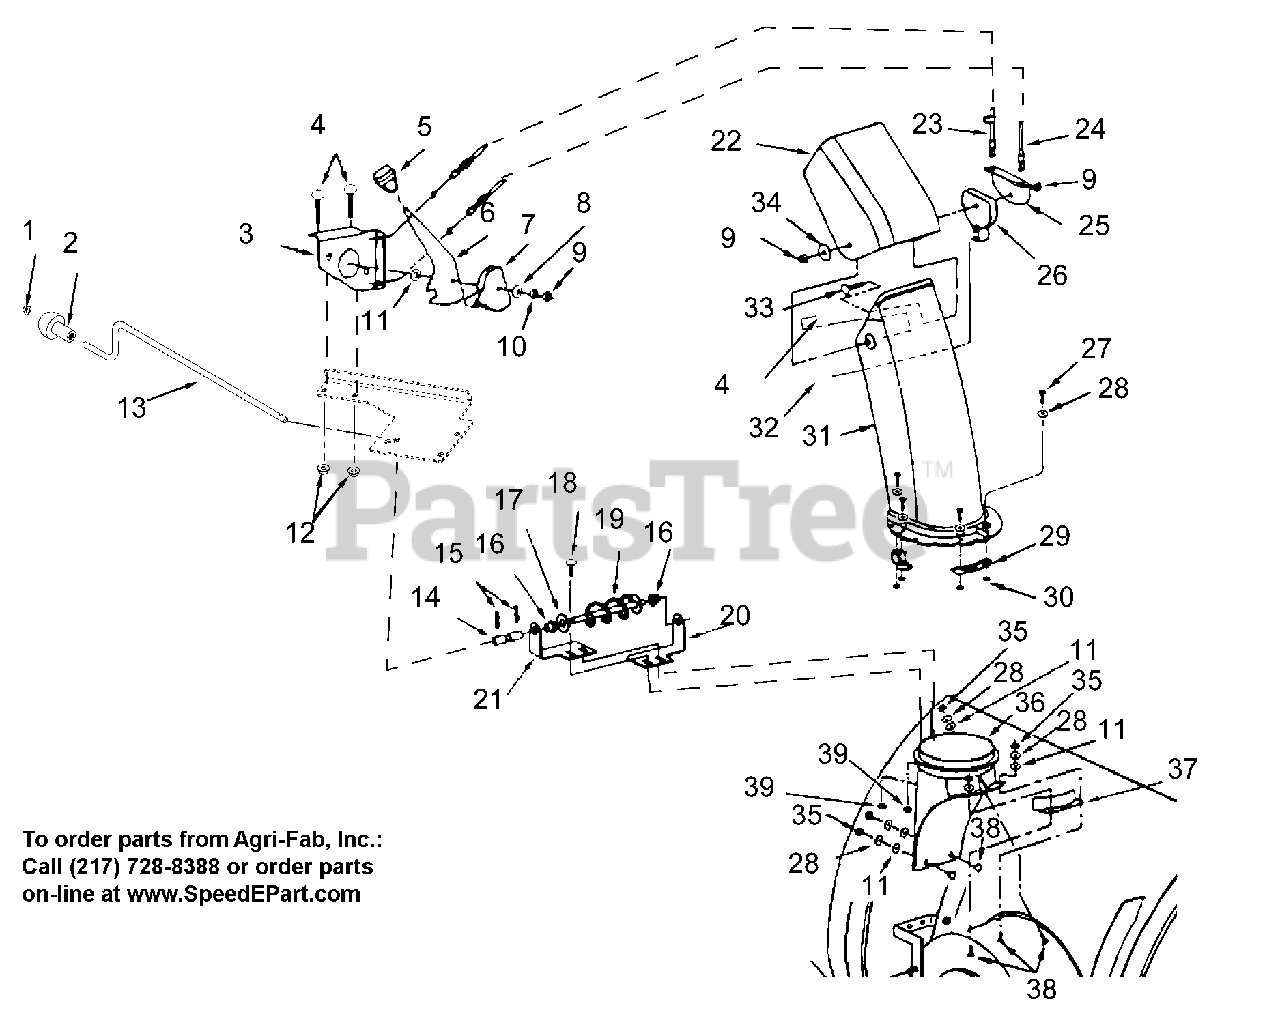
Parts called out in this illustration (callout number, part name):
1	Cap, .38 Rod
2	Knob
3	Assembly, Chute Tilt Bracket
4	Bolt, Round Head Square Neck .31-18 x .75 Grade 5
5	Knob
6	Handle, Chute Tilt
7	Guide, Cable
8	Washer, 5/16
9	Nut, Hex Lock 5-16-18
10	Washer, Locking .31 x .078 Regular
11	Washer, Flat Nylon .375 x .75 x .060
12	Nut, Locking Top Flange .31-18
13	Crank, Chute
14	U-Joint
15	Pin, Spring Clip
16	Plastic Bushing, 3/8
17	Flat Washer, 3/8
18	Carriage Bolt, 5/16-18 x 1
19	Chute Crank Assembly
20	Chute Crank Bracket, Front
21	Chute Crank Bracket, Rear
22	Chute, Upper
23	Cable, Chute Control with Clip
24	Cable, Chute Control
25	Bracket, Cable
26	Guide, Cable
27	Hex Bolt, 1/4-20 x 1
28	Washer, 1/4
29	Chute Keeper
30	Hex Lock Nut, 1/4
31	Chute, Lower
32	Screw, Machine .25-20 x .75 Hex Washer Head
33	Carriage Bolt, 5/16-18 x 1-1/2
34	Washer, 5/16
35	Hex Lock Nut 1/4-20
36	Chute Adapter
37	Chute Reinforcement
38	Carriage Bolt, 1/4-20 x 3/4
39	Nut, Locking Top Flange .31-18
